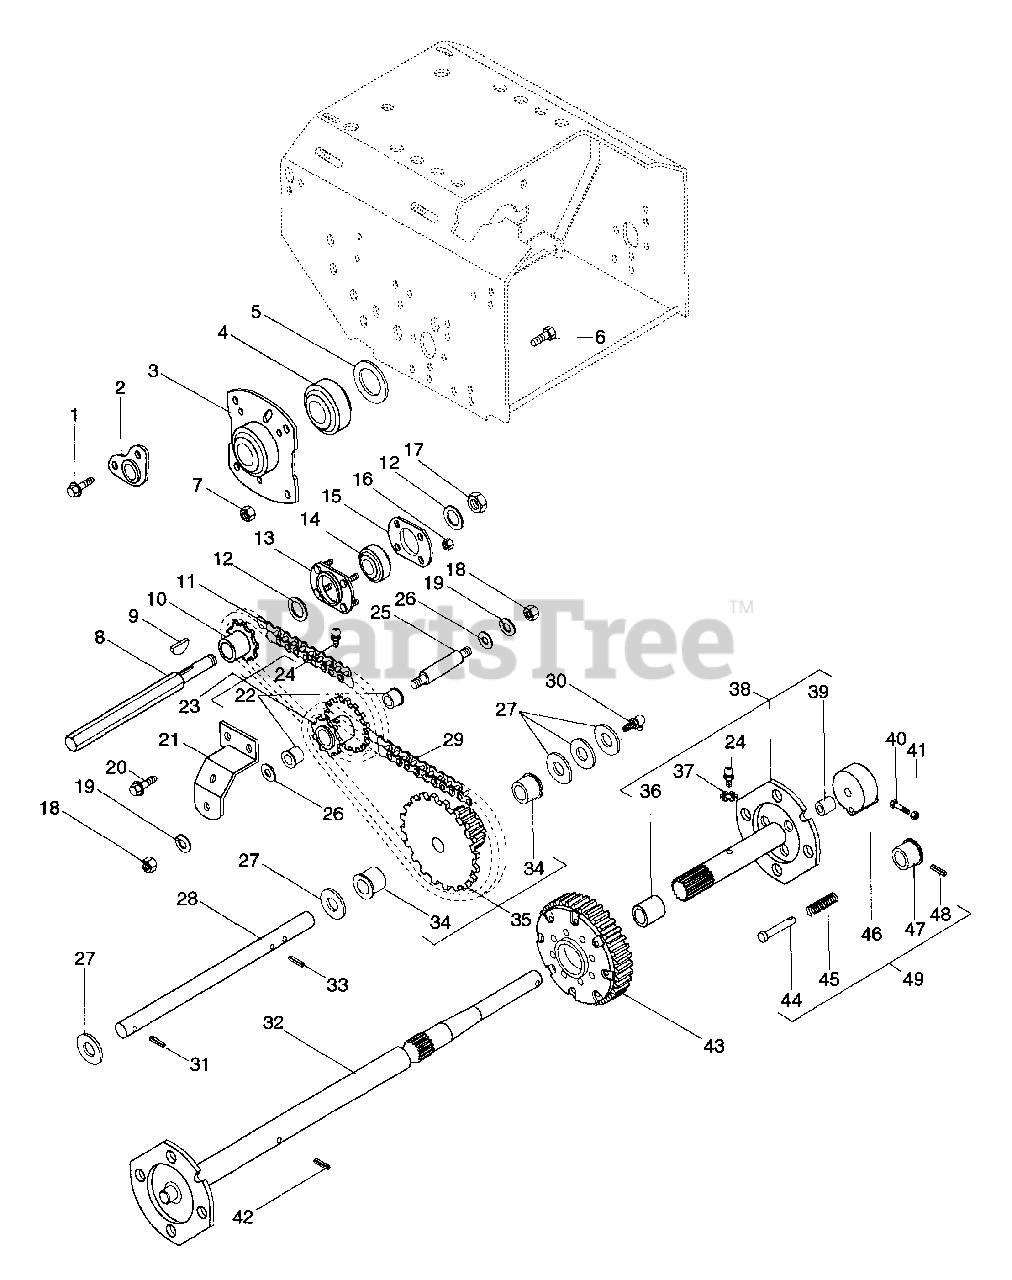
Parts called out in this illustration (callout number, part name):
1	SCR-TAP .250-20X.37 HWH PL TR
2	SUPPORT, SHAFT
3	BEARING RETAINER
4	BRG-BALL 1.13X2.19X.63
5	WSHR-FL-STL 1.140X1.718X.134
6	BLT-SERNK SL .25-20X.50 PL
7	NUT-LK-FLG .250-20 PL
8	HEX SHAFT
9	KEY-WDRF .125X.625X.250 SAE5
10	9 TOOTH SPROCKET
11	ROLLER CHAIN #41 22 PITCHES
12	WSHR-FL-STL .505X.880X.072 PL
13	BEARING FLANGE
14	BRG-BALL .500X1.375X.437
15	BEARING FLANGE
16	NUT-LK DUAL FACE 10-24 PL
17	NUT-LK-CTR .50-20 PL
18	NUT-HEX .375-16
19	WSHR-LK .375X.130
20	SCR-TAP .250-20X.50 HXSLHDPL
21	SUPPORT, SHAFT
22	BSHG-SLV .500X.625X.500 BR
23	SPROCKET ASSEMBLY
24	FTG-LUBE .25-28X.256 YWZC
25	REDUCTION SHAFT
26	WSHR-FL-STL .382X.812X.062
27	WSHR-FL-STL .630X1.005X.062 PL
28	PINION SHAFT
29	ROLLER CHAIN #41 38 PITCHES
30	HYDRAULIC DRIVE FITTING
31	PIN-ROLL .156X1.00
32	R H AXLE
33	PIN-ROLL .125X1.00
34	BSHG-FLG .625X.750X.500X.875BR
35	PINION & SPROCKET ASSEMBLY
36	BSHG-SLV .750X.814X .750 BRZ
37	WSHR-LK .250X.047 LT PL
38	L.H. AXLE ASSEMBLY
38	L.H.AXLE ASSEMBLY
39	BSHG-SLV .562X.625X.625 BRZ
40	BLT-HEX .25-20X2.0 GR8 PL
41	NUT-JAM-NYL .250-20 W/INSRT
42	PIN-ROLL .188X1.50
43	DIFFERENTIAL ASSEMBLY
45	SG-COMP .028X.34X1.062 WLD75
46	LOCKOUT HUB
48	PIN-ROLL .093X1.00
49	LOCKOUT HUB ASSEMBLY
